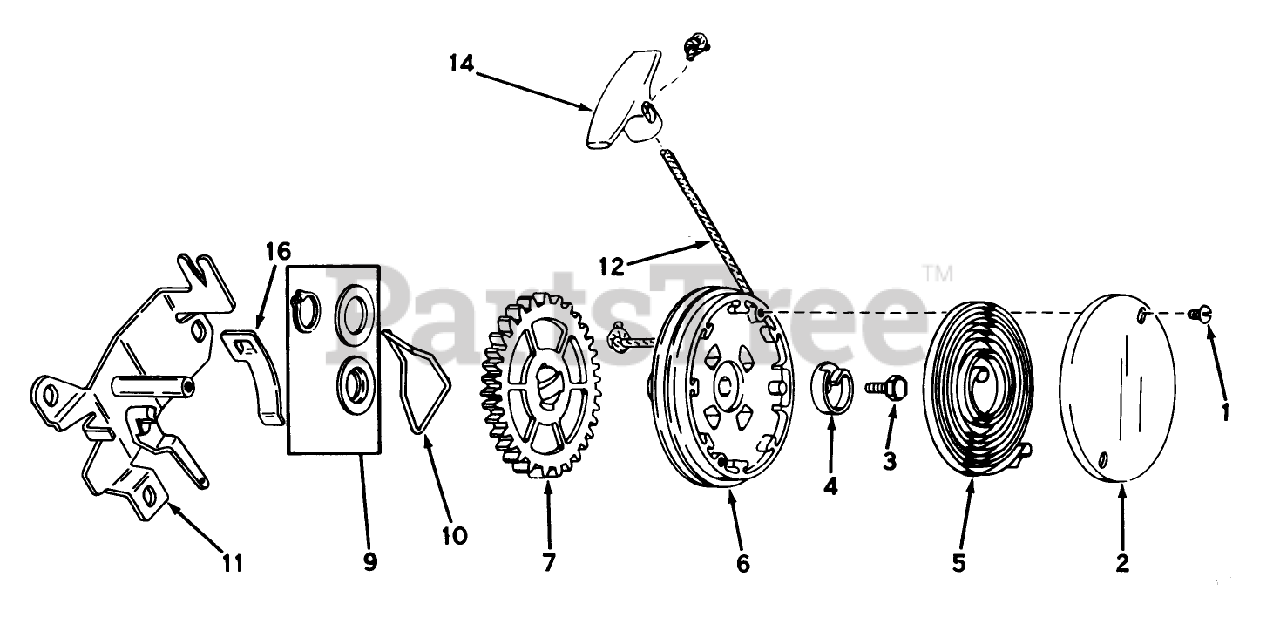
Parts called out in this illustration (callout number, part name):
2	Cover, Spring
3	Screw, Hex Washer Head
4	Hub Spring
5	Spring, Rewind
6	Pulley Assy. (Incl. Ref. #9)
9	Kit, Thrust Wash. & Snap Rg.
11	Bracket Assy., Mounting
12	Rope, Starter
14	Handle-Starter
16	Clip Rope
